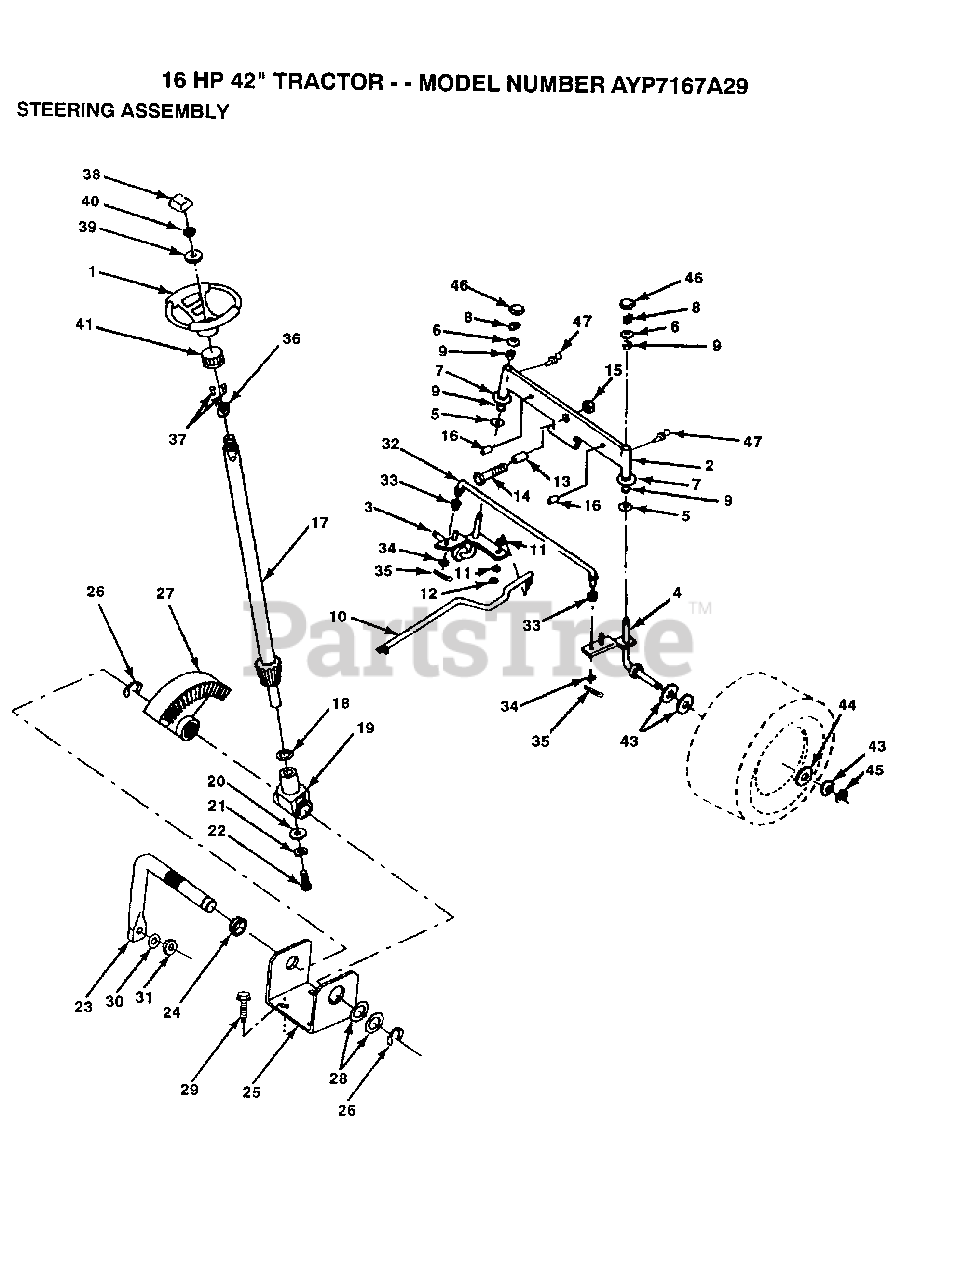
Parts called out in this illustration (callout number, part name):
3	SPINDLE LH
4	SPINDLE RH
5	WASHER .T
6	WASHER
7	WASHER
8	RING
9	COL. SRTG. BEAR.
11	LOCKWASHER
13	BEARING
14	BOLT HEX 5/8-11
16	AXLE PIN
17	STEERING SHAFT
18	THRUST WASHER
19	SUPPORT.SHAFT
21	LOCKWASHER
22	"SCREW,SPECIAL"
24	NYLINER T
25	"BRKT,STEERING"
26	RING
28	WASHER .T
29	SCREW
30	LOCKWASHER
32	TIE ROD
33	BUSHING.DRAGLINK
34	WASHER
35	COTTER PIN
38	ST WHL INSERT CAP
39	WASHER
41	ADAPTER LT
43	WASHER
44	WASHER
45	RING
46	CAP
47	ZERK M
